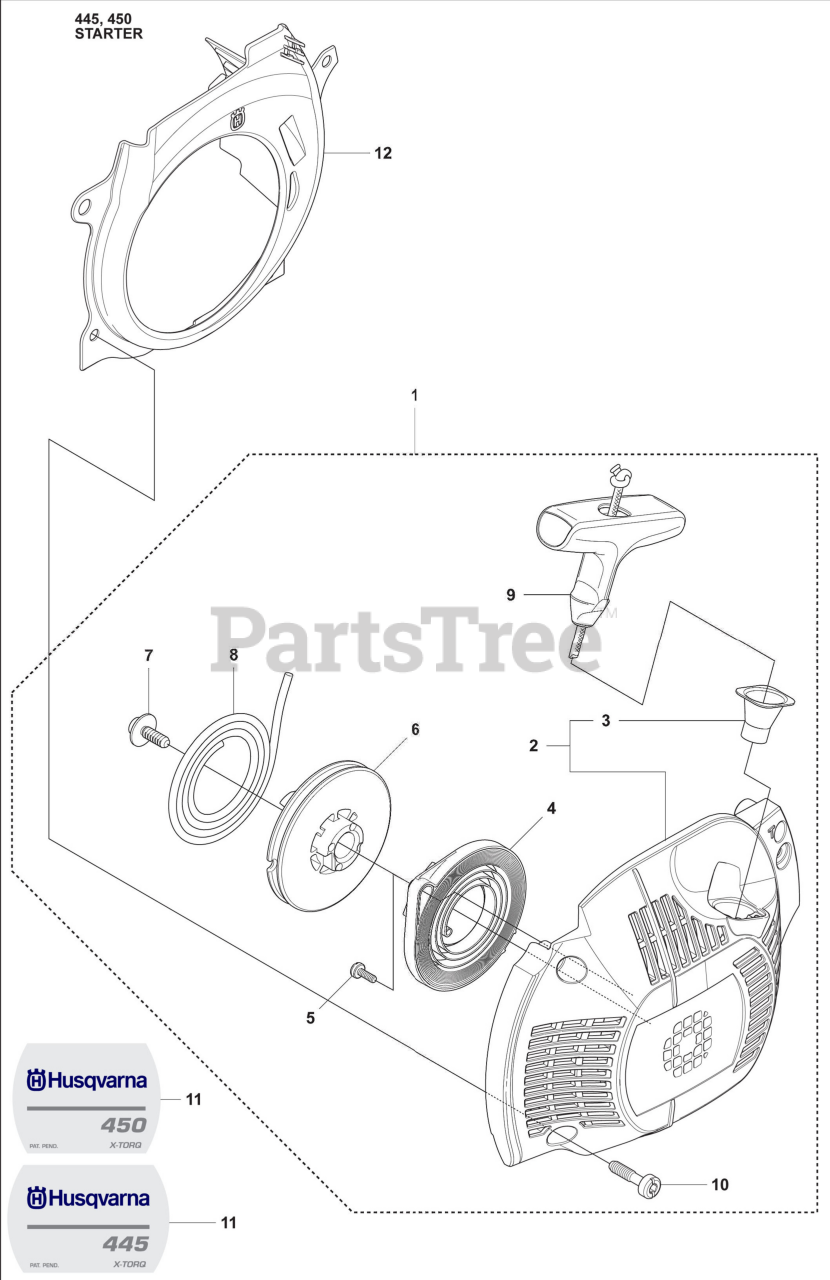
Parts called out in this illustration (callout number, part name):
1	Starter Assembly
2	Starter Housing
4	Return Spring
6	Starter Pulley
8	Starter Rope
10	Recoil Starter Screw
11	Label
12	Air Cooling Conductor
